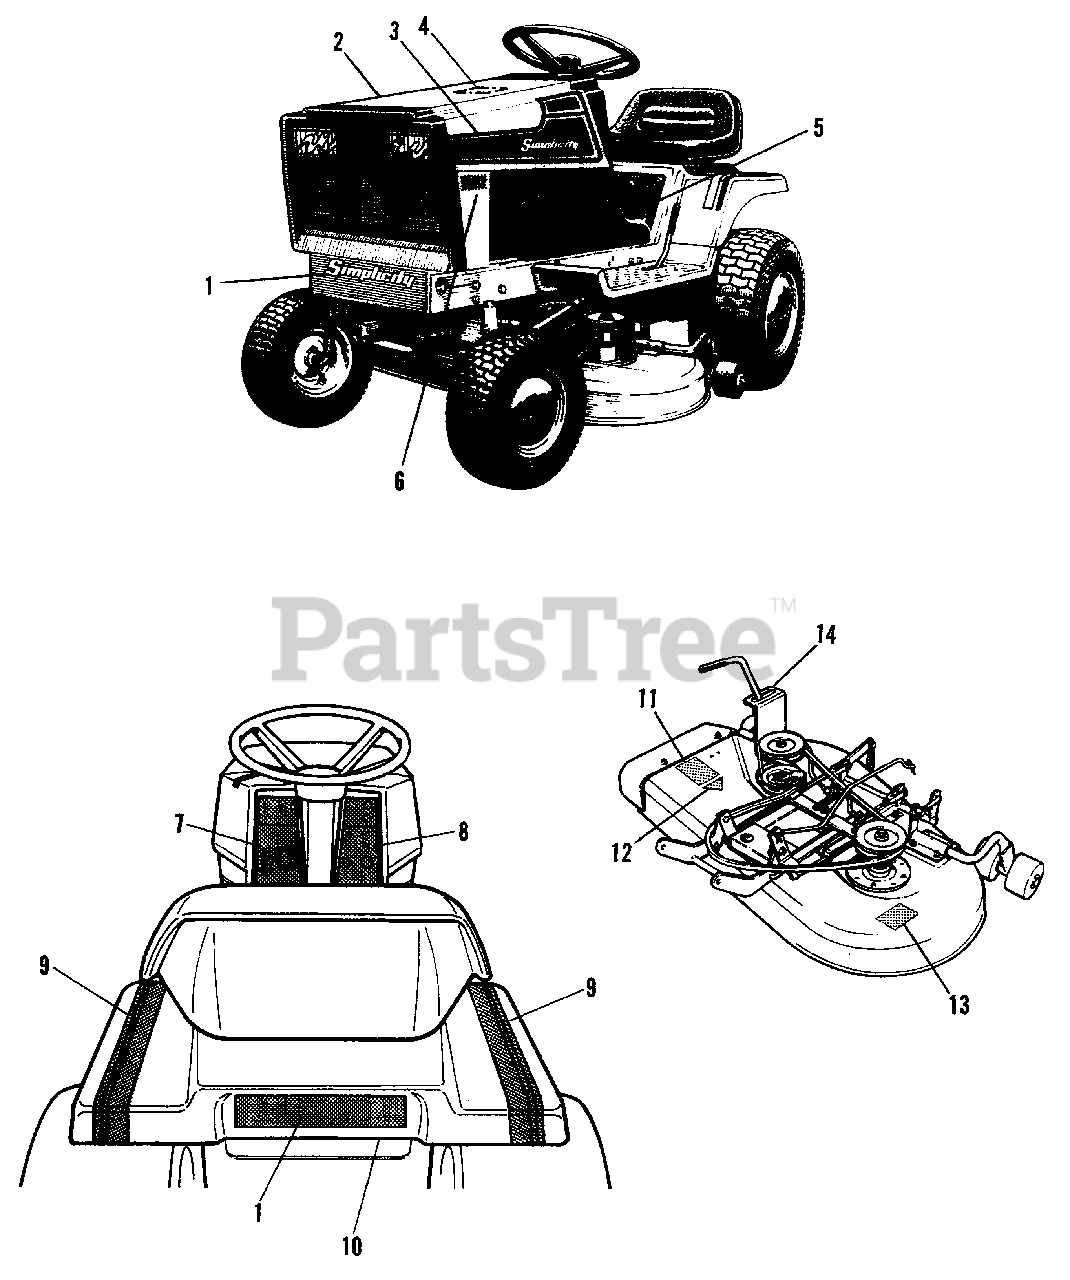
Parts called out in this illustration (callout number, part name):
1	DECAL, Simplicity
2	DECAL, Hood, R.H.
3	DECAL, Hood, L.H.
4	DECAL, Drive Belt
5	DECAL, Shift Pattern
6	DECAL, 4208 Electric
6	DECAL, 4211 Electric
7	DECAL, Dash, L.H. Side
8	DECAL, Dash, R.H. Side
9	DECAL, Seat Deck
10	DECAL, Battery, Simplicity
11	DECAL, Danger
12	DECAL, OPEI
13	DECAL, Danger
14	DECAL, Mower Height
